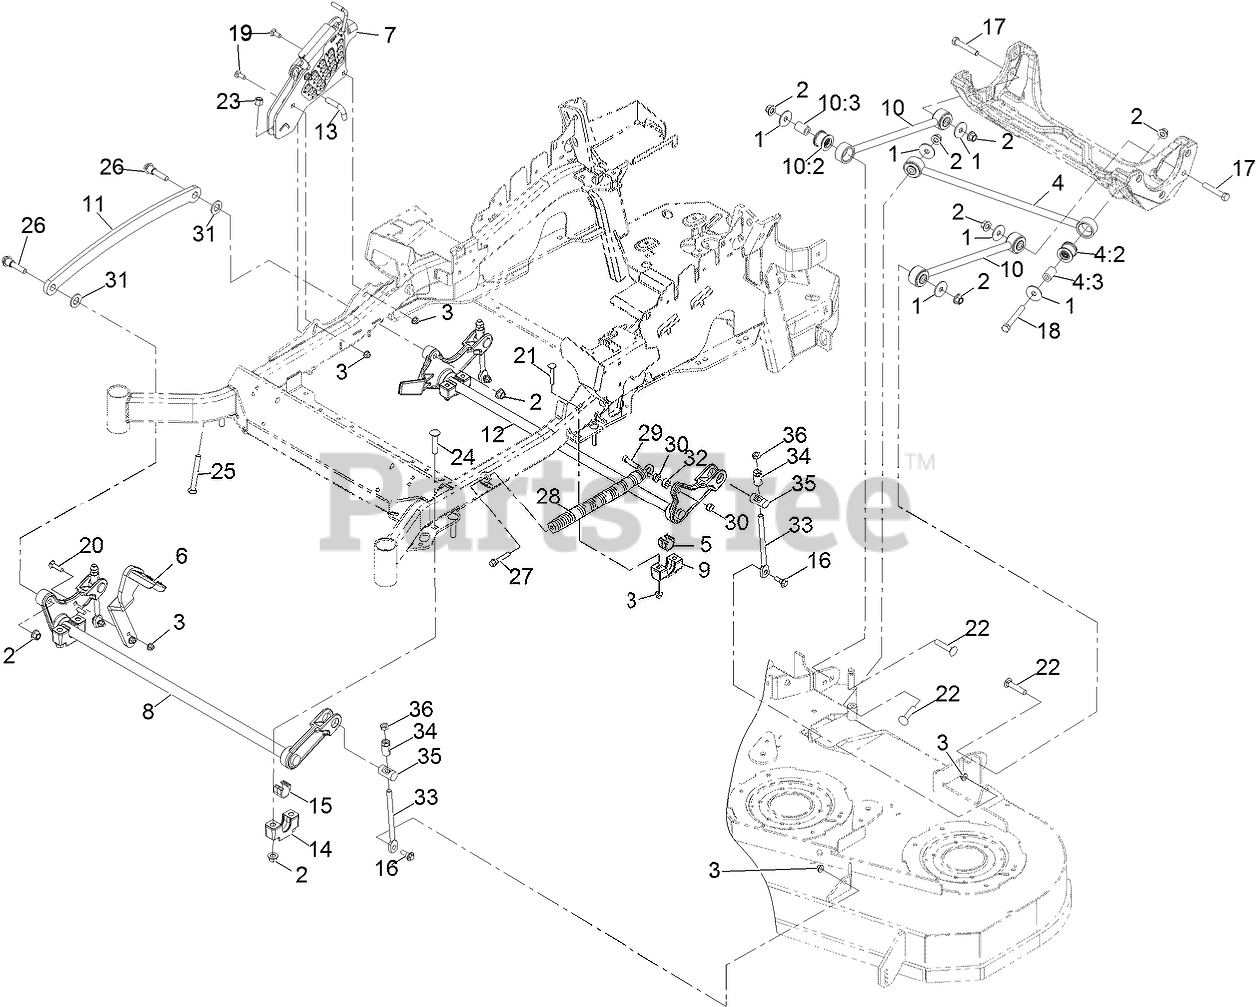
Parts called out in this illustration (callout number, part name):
1	WASHER-THRUST
2	Nut-Lock 1/2-13
3	NUT-HF, NI
4	PANHARD ROD ASM
4:2	BUSHING-SUSPENSION, RUBBER
5	BEARING-CROSS SHAFT, REAR
6	LEVER-FOOT
7	HOC ASM
8	DECKLIFT-FRONT
9	SUPPORT-CROSS SHAFT, BEARING REAR
10	DECK STRUT ASM
10:2	BUSHING-SUSPENSION, RUBBER
11	LINK-LIFT, DECK
12	LIFT-DECK, REAR
13	PIN-HOC
14	SUPPORT-CROSS SHAFT, BEARING
15	BEARING-CROSS SHAFT, FRON
16	SCREW-SHOULDER, HHF
17	SCREW-HH
18	SCREW-HH
19	BOLT-CARR
20	SCREW-CARR
21	Bolt-Carriage 3/8-16 X 2 1/4
22	SCREW-CARR
23	NUT-LOCK, NI
24	Bolt-Carriage 1/2-13 X 2 1/2 Spl Neck
25	BOLT-TAP
26	SCREW-HHF, SHOULDER
27	BOLT-SHOULDER
28	SPRING-EXTENSION
29	SCREW-HH
31	WASHER-FLAT
33	LINK-ADJUSTER, DECK LIFT
34	ADJUSTER-LIFT, DECK
35	TRUNNION
36	NUT-JAM
